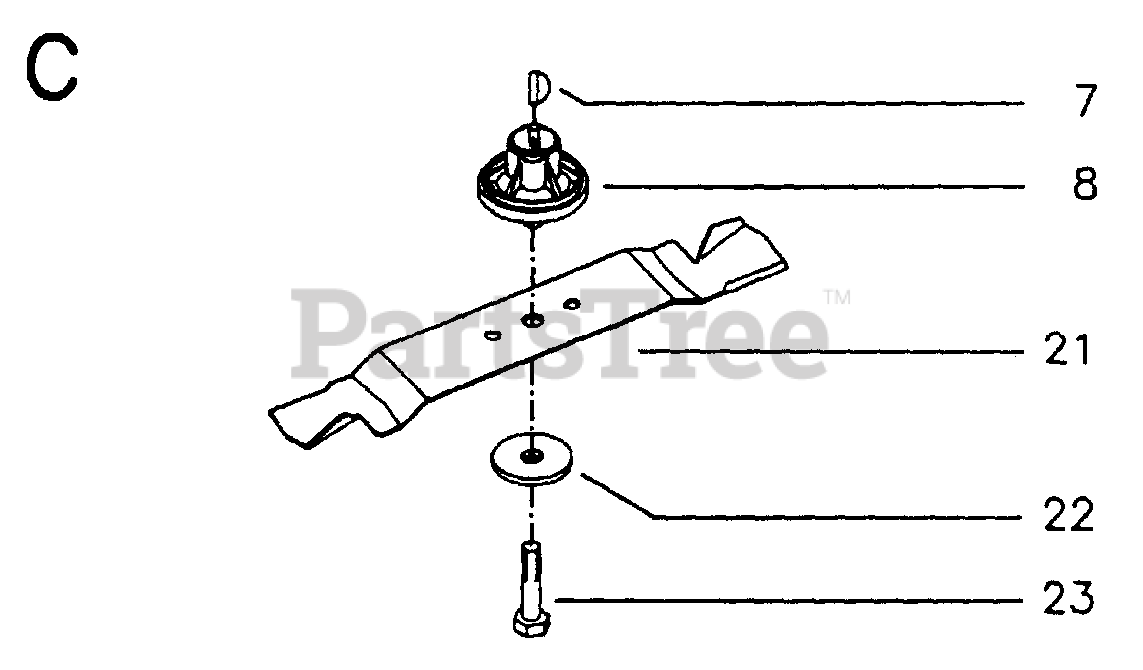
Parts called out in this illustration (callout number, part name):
7	WOODRUFF KEY
8	BLADE ADAPTER
21	BLADE
23	REPL BY 515 12 39-31
